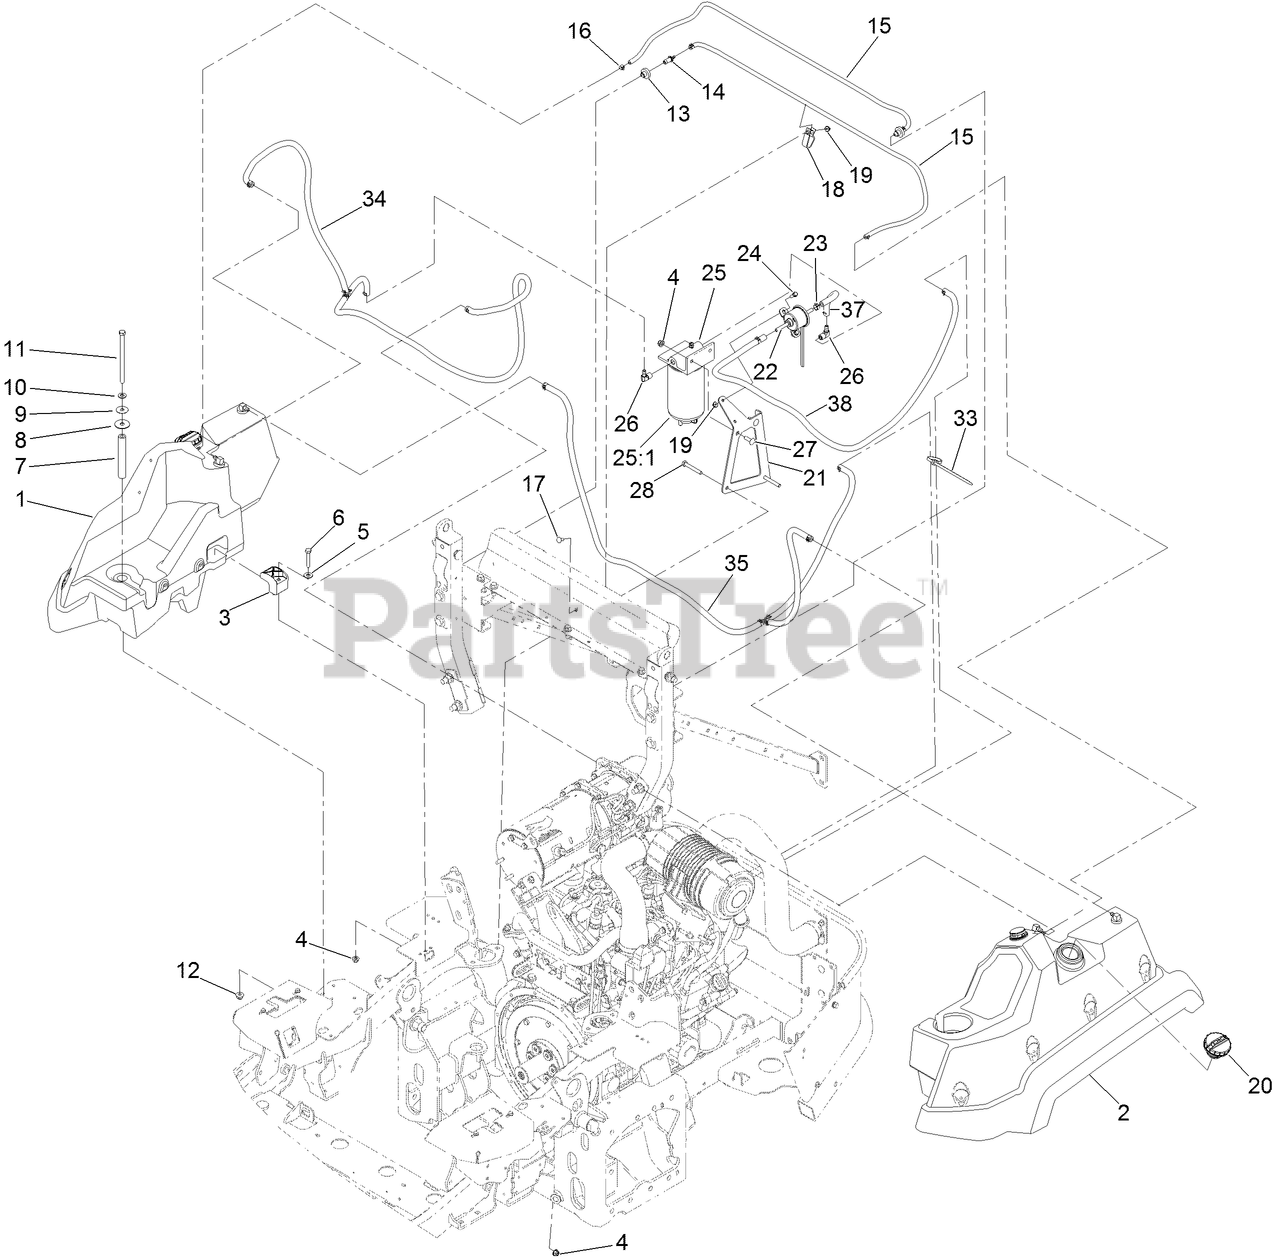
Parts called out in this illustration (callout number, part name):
1	RH FUEL TANK ASM
2	LH FUEL TANK ASM
4	NUT-HF, NI
5	WASHER-FLAT
6	SCREW-HH
7	TUBE-SPACER
8	WASHER-RUBBER
9	WASHER-PLAIN
10	WASHER-FLAT
11	SCREW-HH
12	NUT-HF, NI
13	BUSHING
14	FITTING-ORIFICE, STRAIGHT
15	HOSE-VENT, TANK
16	CLAMP-HOSE
17	SCREW-CARR
18	CLAMP-HOSE
19	NUT-HF
20	CAP-FUEL, DIESEL
21	BRACKET-FILTER, FUEL
22	PUMP-FUEL, ELECTRIC
23	CLAMP-HOSE
24	SCREW-HWH
25	SEPARATOR FILTER ASM
25	FILTER-WATER/FUEL SEPERATOR
25:1	FILTER-FUEL/WATER SEPARATOR
26	FITTING-HYD, 90
27	SCREW-CARR
28	SCREW-HH
33	TIE-PLASTIC
34	FUEL SUCTION LINE ASM
35	FUEL RETURN LINE ASM
37	HOSE-FUEL
38	HOSE-FUEL
